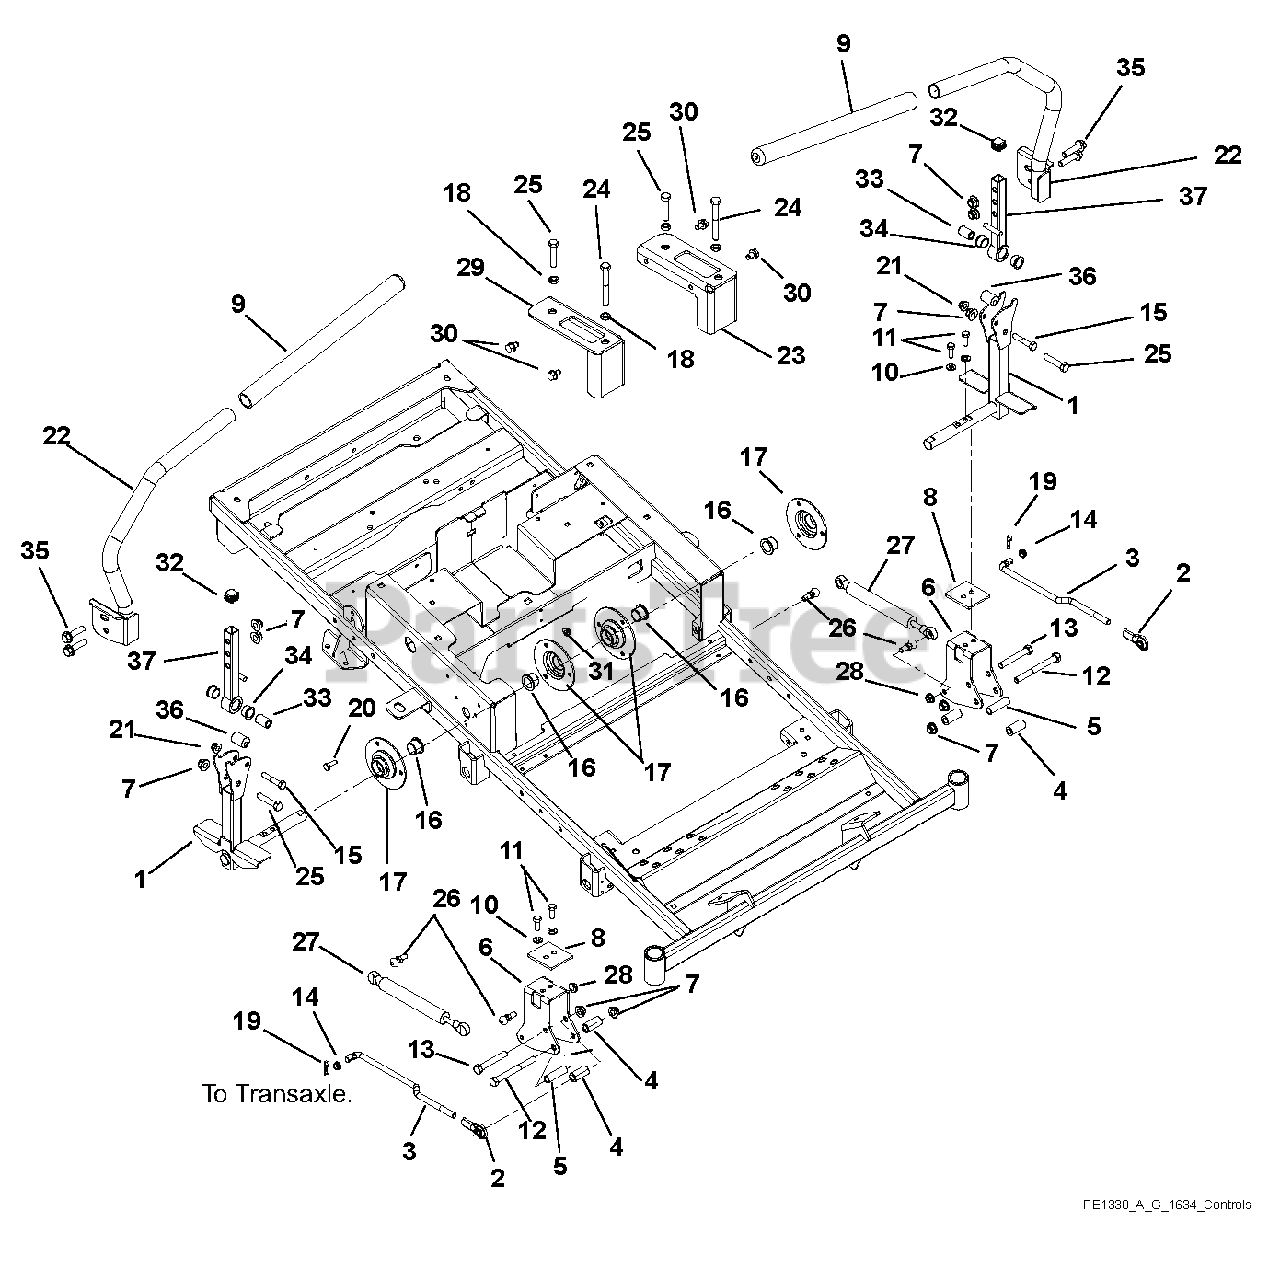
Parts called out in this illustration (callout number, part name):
1	WMT, CONTROL ARM
2	ROD END, .38 RH
3	LINK, TRANSMISSION
4	BSHG, SPCR .390X.625X1.25 PM
5	SPACER, STEERING
6	BRKT, STEERING
7	@NUT-LK-NYL-FLG .38-16 YWZC
8	PLATE, STEERING REINFORCING
9	GRIP, HANDLEBAR 15" FOAM
10	@WSHR-LK .31X.078 REG YWZC
11	BLT-HEX .31-18X1.00 GR8 YWZC
12	@BLT-HEX .38-16X3.75 GR5 YWZC
13	@BLT-HEX .38-16X2.50 GR5 YWZC
14	BUSHING, POLYLINER-.38 SNAPIN
15	@BLT-HEX .31-18X1.75 GR5 YWZC
16	BSHG-FLG .750X1.000X.625X1.250
17	BEARING FLANGE
18	NUT-HEX-JAM .375-16 YWZC
19	PIN-HAIR INT .08X.18X1.18 YWZC
20	@BLT-HEX .25-20X.75 GR5 YWZC
21	@NUT-LK-NYL-FLG .31-18 YWZC
22	WMT, STEERING HANDLE RH
23	BRACKET, LH SPEED CONTROL
24	BLT-HEX .38-16X3.00 GR5 FTH YZ
25	BLT-HEX .375-16X1.750 FTD YWZC
26	STUD- BALL
27	DAMPER, CONTROL
28	@NUT-LK-TOP-FLG .31-18 YWZC
29	BRACKET, RH SPEED CONTROL
30	@SCR-TAP .31-18X.50 HWH TR YWZ
31	@NUT-LK-TOP-FLG .25-20 YWZC
32	CAP PLUG, SQ 3/4-14-20 RIBBED
33	SPACER, .375X.625X.970 (PM)
34	BSHG-FLG, .625X.75X.450X.875
35	BOLT, SERRATED HEAD .38-16X1.5
36	BSHG, ECCENTRIC .328X.750X.970
37	WMT, UPPER CONTROL ARM
